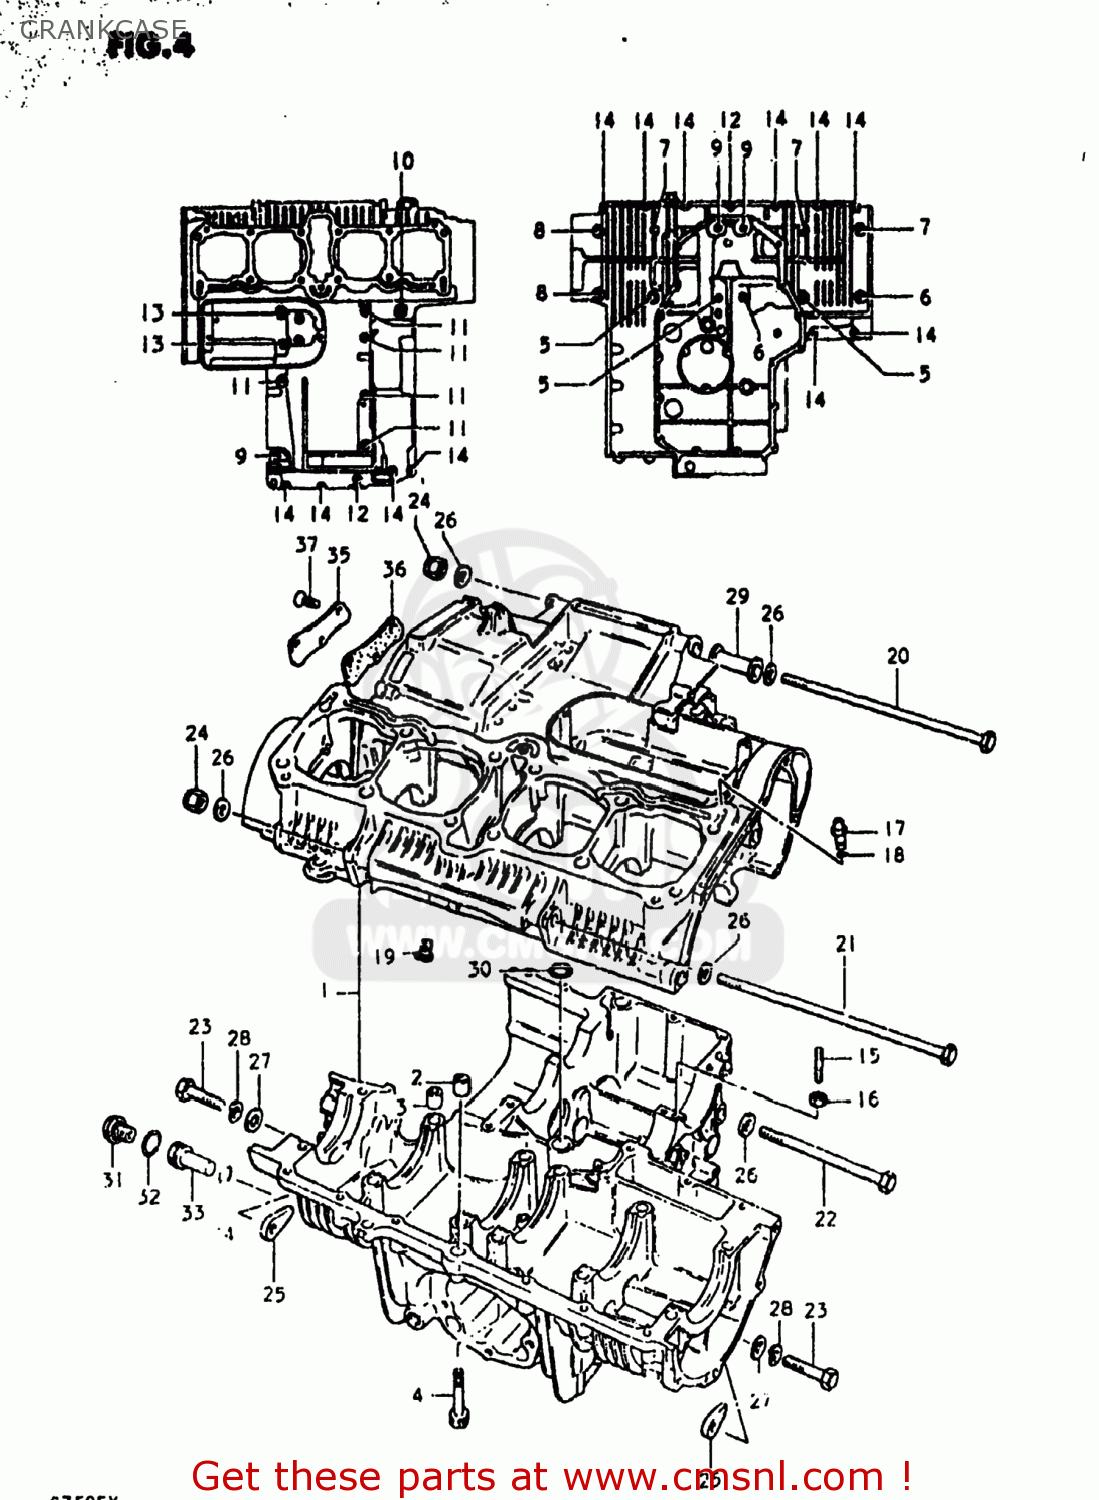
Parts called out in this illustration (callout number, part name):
1	CRANKCASE SET
2	PIN(10.4X13X22)
3	PIN (11X20)(SUS)
4	BOLT
5	BOLT
6	BOLT
7	BOLT (8X95)
8	BOLT (8X70)
9	BOLT 8X65
10	BOLT 6X95
11	BOLT (6X80)
12	BOLT (6X60)
13	BOLT,UNDER
14	BOLT
15	STUD BOLT
16	NUT
17	JET
18	O-RING
19	JET,AIR
20	BOLT 10X230
21	BOLT 10X250
22	BOLT(10X165)
23	BOLT 10X60
24	NUT
25	NUT
26	WASHER
27	WASHER(10.5X20X3.2)
28	LOCK WASHER
29	SPACER,ENGINE MOUNT
30	O RING(D:3.2,ID:12.9)
31	PLUG
32	O RING(D:2.4,ID:17.8)
33	PIN,OIL GALLERY
34	SEAL (D:1.9 ID:9.8)
35	CAP,OIL GALLERY
36	GASKET,OIL GALLERY (MCA)
37	SCREW
